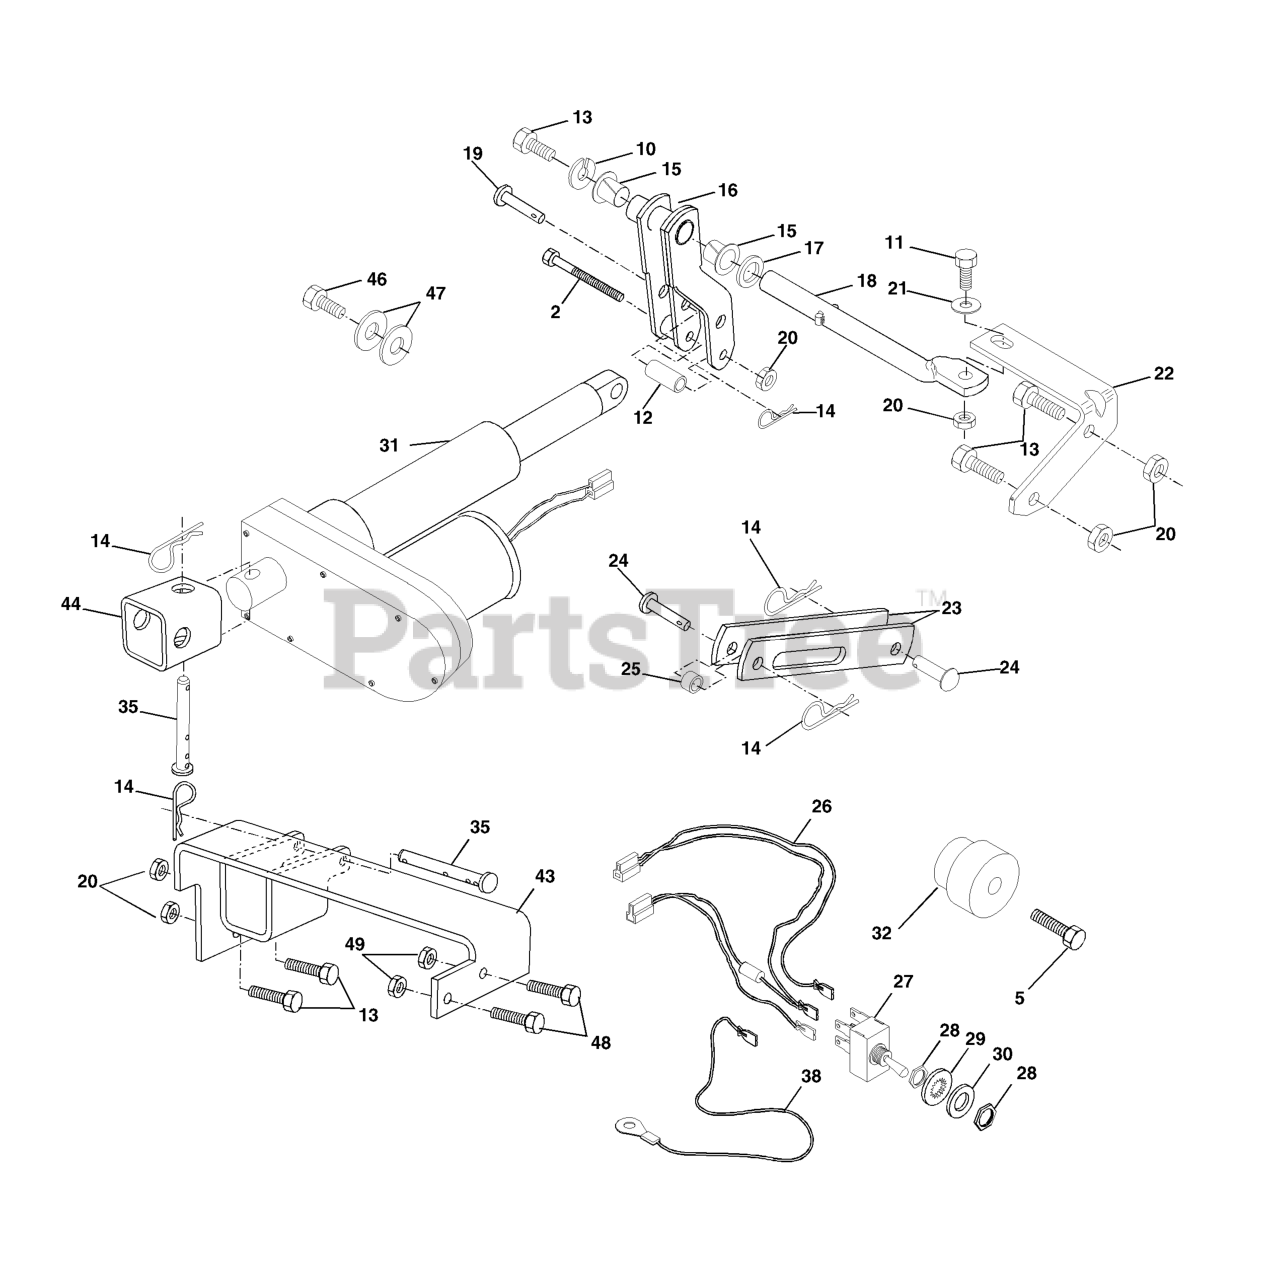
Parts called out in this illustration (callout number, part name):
2	Bolt, Hex 3/8-16 x 3-1/4 Grade 5
5	Bolt, Hex 3/8-16 x 1-3/8
10	Washer, Lock
11	Bolt, Hex 3/8-16 x 1-1/4
12	Bushing .384 x 1/2 x 1-1/4
13	Bolt, Hex 3/8-16 x 7/8
14	Spring, Retainer
16	Arm, Pivot
17	Washer 21/32 x 1 x 21 Ga.
18	Rod, Pivot Support
19	Pin, Pivot 5/8 x 1-1/2
20	Locknut 3/8-16
21	Washer 13/32 x 7/8 x 16 Ga.
22	Bracket, Pivot Rod
23	Link, Lift
24	Pin, Pivot 1/2 x 3/4
25	Spacer
26	Harness, Lift Kit
27	Switch, Lift
28	Nut, Switch
29	Washer, Lock Int. Tooth
30	Washer 15/32 x 3/4 x 16 Ga.
31	Electric, Actuator
32	Hub, Lever Lift (Tapered)
35	Pin, Pivot 2-1/2"
38	Wire, Ground
43	Bracket, Frame
44	Tube, Pivot
46	Screw 5/16-18 x 1-1/4
47	Washer 11/32 x 1-1/2 x 10 Ga.
48	Bolt, Hex 5/16-18 x 7/8
49	Locknut 5/16-18
